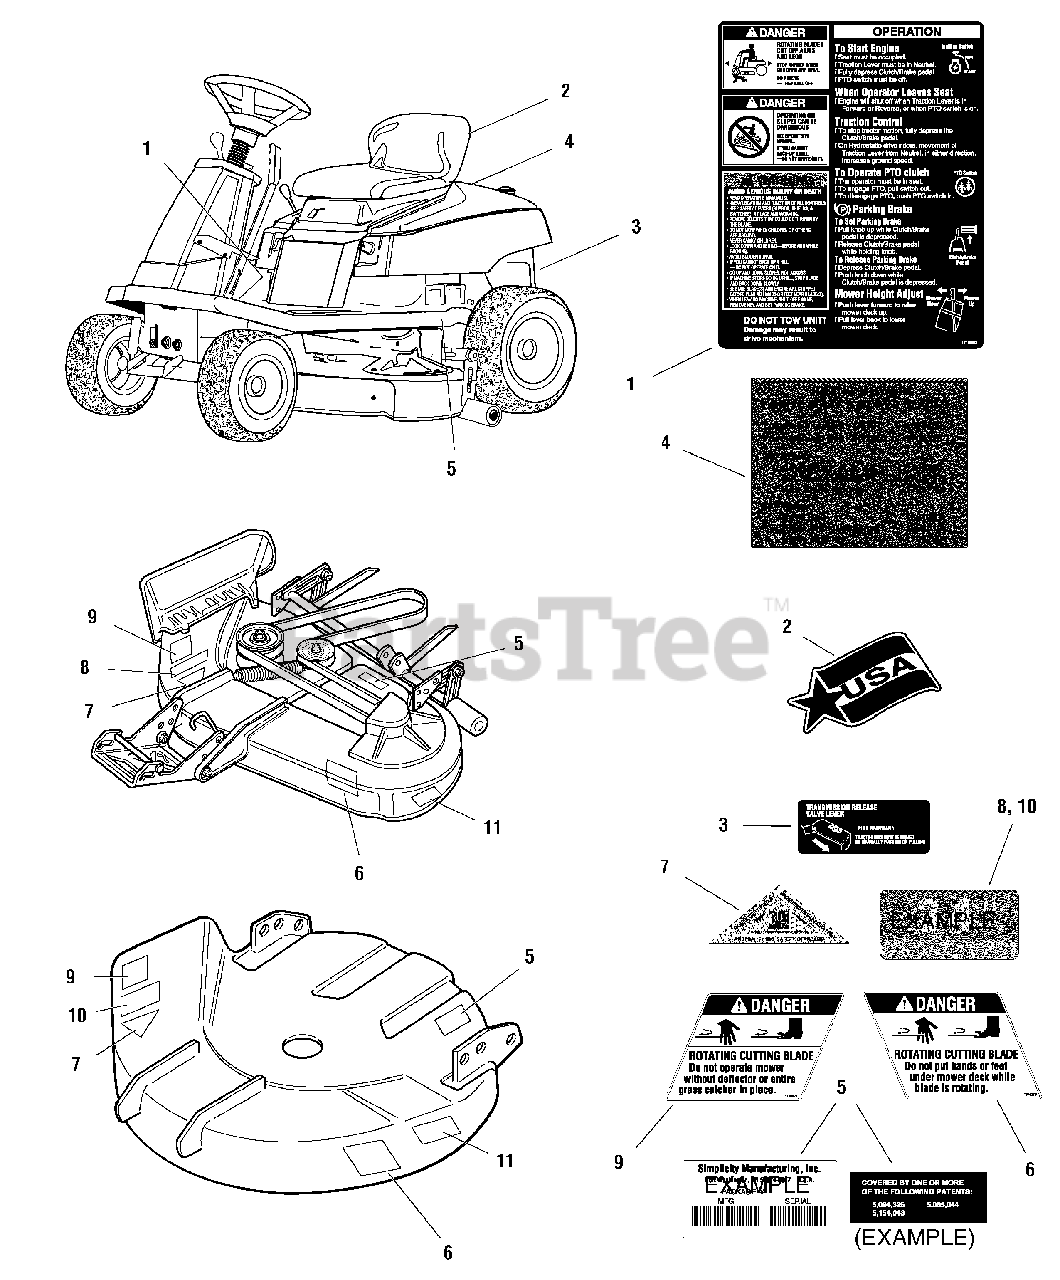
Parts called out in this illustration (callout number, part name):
1	DECAL, Operating Instructions, English
1	DECAL, Operating Instructions, Export
3	DECAL, Transmission Release (Hydro models only)
4	DECAL, Belt & Blade Replacement
5	I.D. PLATE (Not Serviced)
6	DECAL, Danger, Rotating Cutting Blade
7	DECAL, OPEI, (Not Serviced)
8	DECAL, Cutting Width - 34", Silver on Black
9	DECAL, Danger, Chute In Place
10	DECAL, Cutting Width - 30", Silver on Black
11	DECAL, Free Floating Mower
